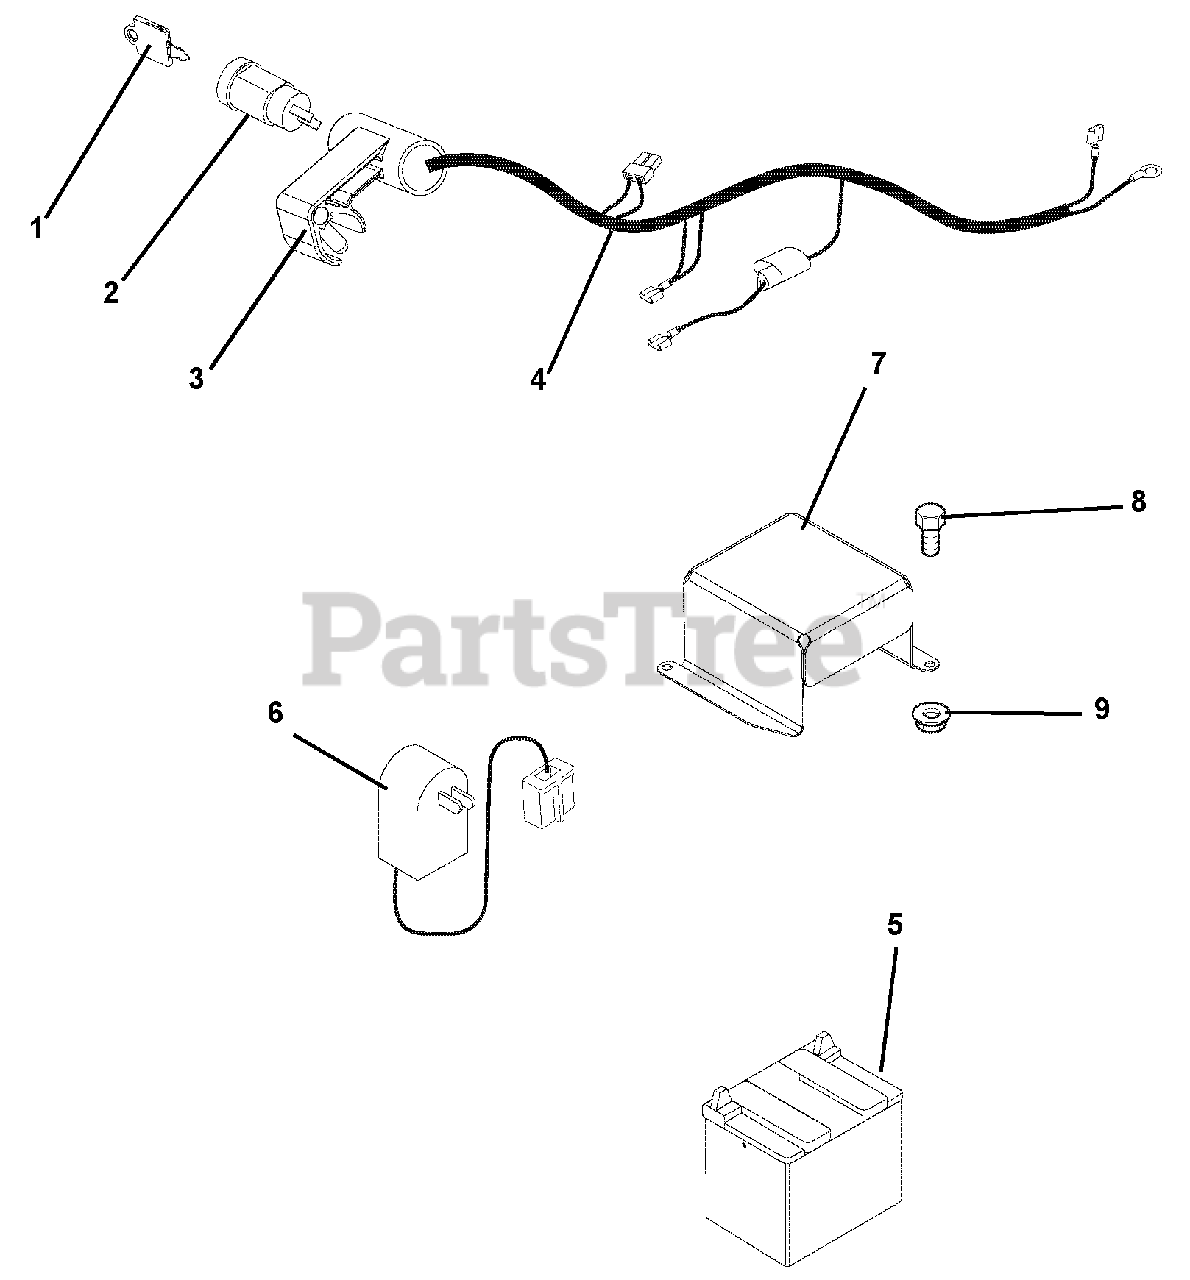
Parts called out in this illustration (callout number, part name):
1	KEY -W/CAP
2	KEYSWITCH
3	SNAP-ON E-START HOUSING
4	HARNESS, WIRE (WBLM)
5	BATTERY - 12V
6	CHARGER, BATTERY (WBLM)
7	COVER, BATTERY
8	@BLT-HEX 8-32 X .5 YWZC
9	@NUT-LK-NYL 8-32 W/INSTR YWZC
